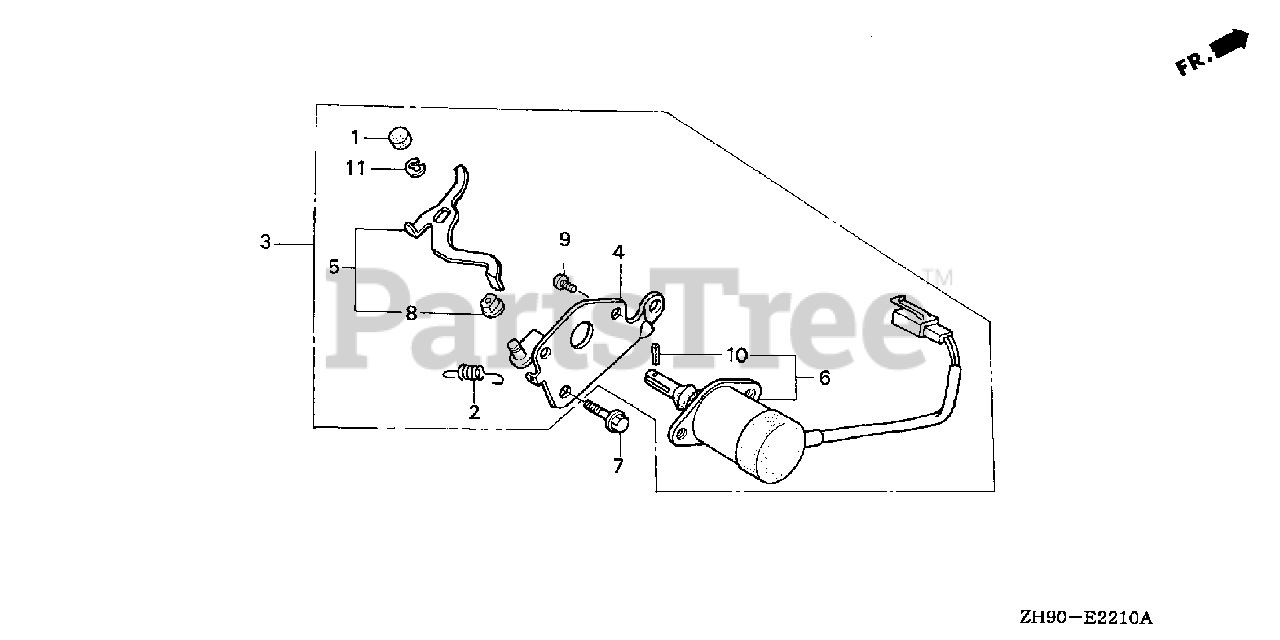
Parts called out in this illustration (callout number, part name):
1	CAP, CHOKE LEVER
2	SPRING, CHOKE RETURN
3	THROTTLE ASSY., AUTO
4	STAY, SOLENOID THROTTLE
5	LEVER, SOLENOID THROTTLE
6	SOLENOID ASSY.
7	BOLT, FLANGE (6X12) (CT200)
8	BUSH, AUTO-THROTTLE LEVER
9	SCREW, PAN (5X8)
10	PIN, SPRING (2.5X16)
11	E-RING (4MM)
